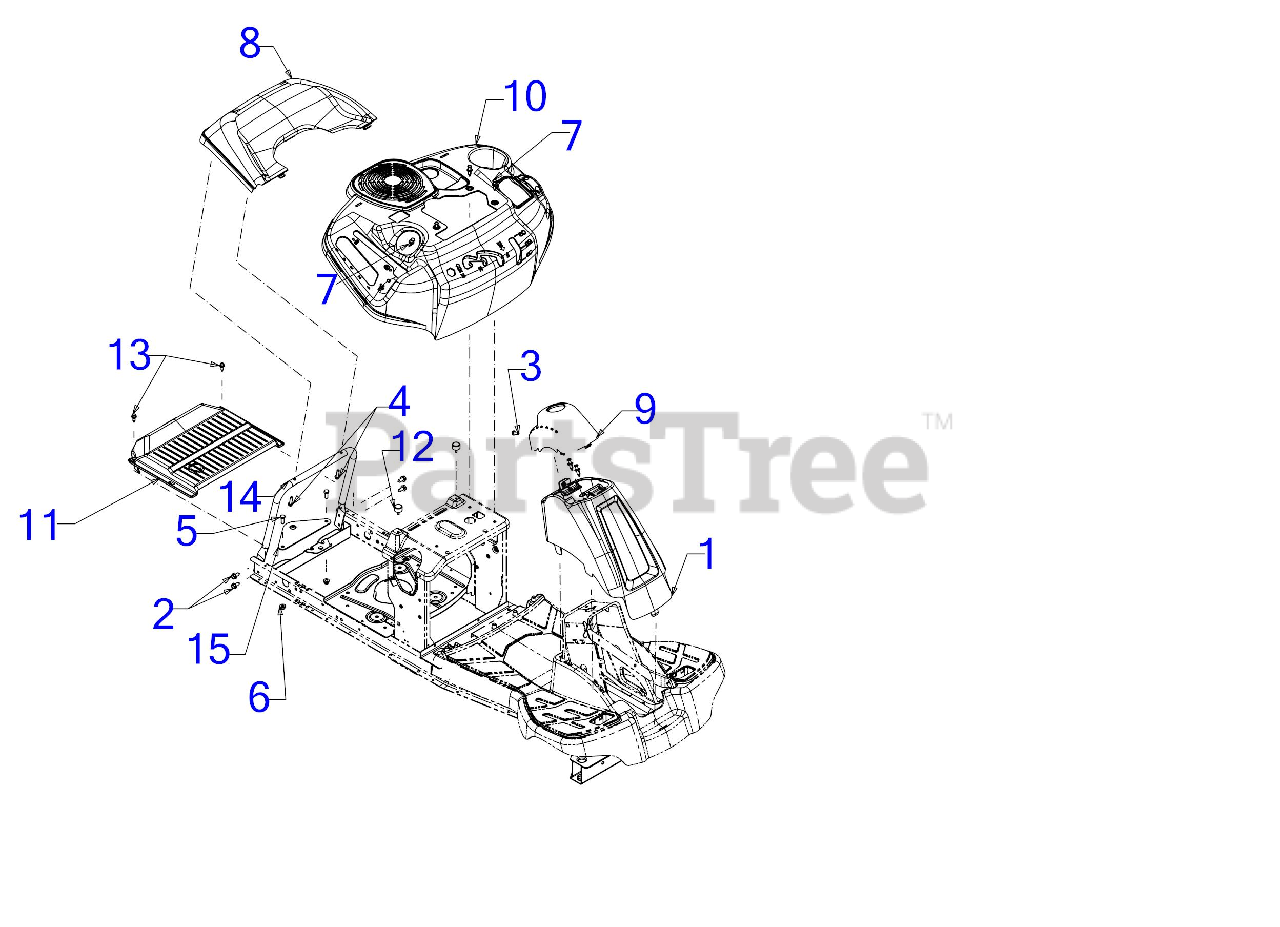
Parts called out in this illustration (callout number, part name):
1	COLUMN COVER ASSEMBLY (MTD RED)
2	SCREW 5/16-18 x .750
3	SCREW 1/4-20X.75
4	SCREW 1/4-15 x 1.00
5	SCREW 5/16-18 x .75 GR5
6	FLANGE LOCK NUT 5/16-18
7	PLASTIC RIVET
9	COLUMN STEERING CAP
10	FENDER
11	CVT DRIVE COVER
12	BUMPER .62 DIA x .50
13	SHOULDER SCREW
15	HITCH PLATE
